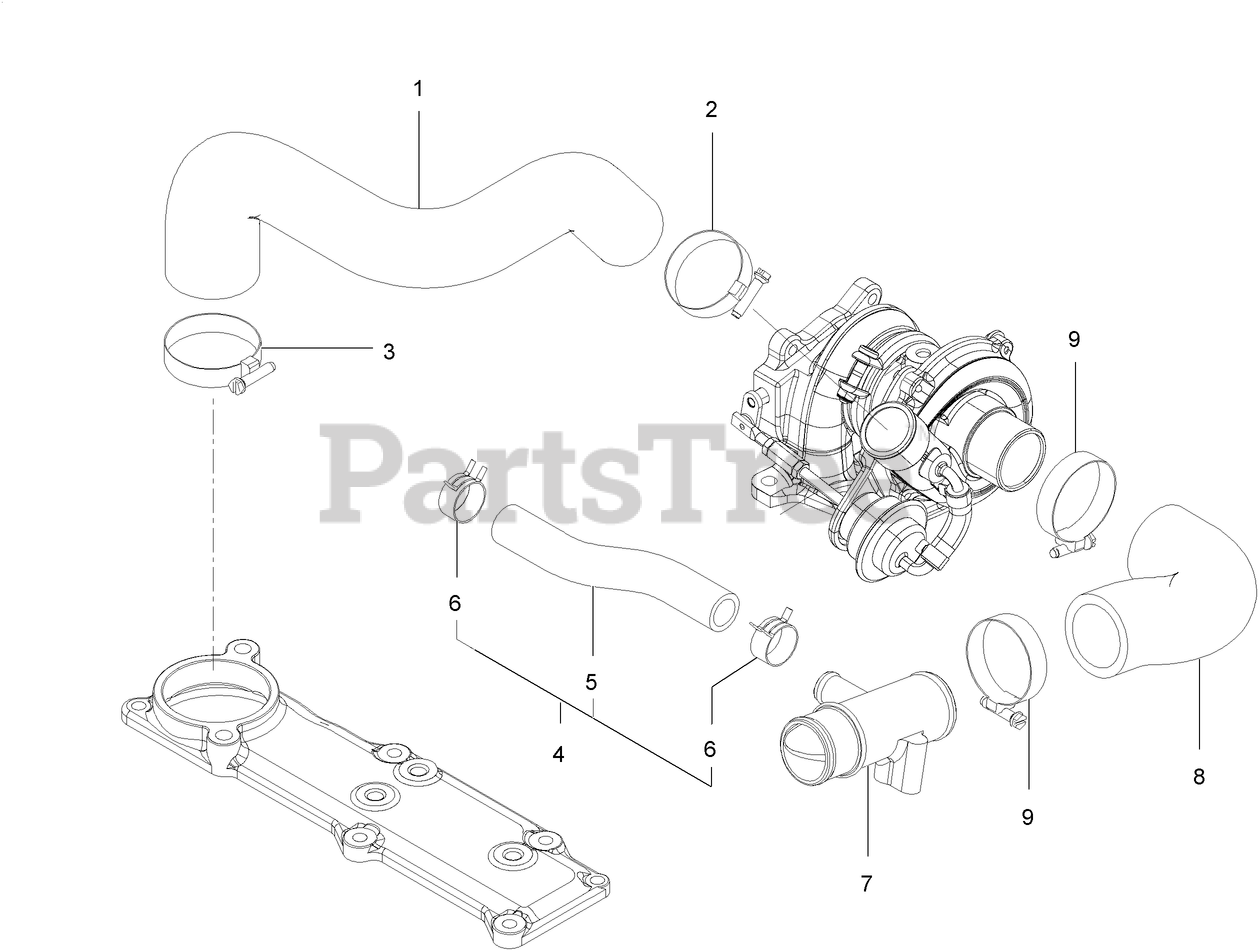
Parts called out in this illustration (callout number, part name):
1	HOSE-AIR INTAKE
2	CLAMP-HOSE
3	CLAMP-HOSE
4	HOSE ASM-BREATHER
5	Hose-Breather
6	CLIP-HOSE
7	JOINT-BREATHER
8	HOSE-AIR INTAKE
9	CLAMP-HOSE
